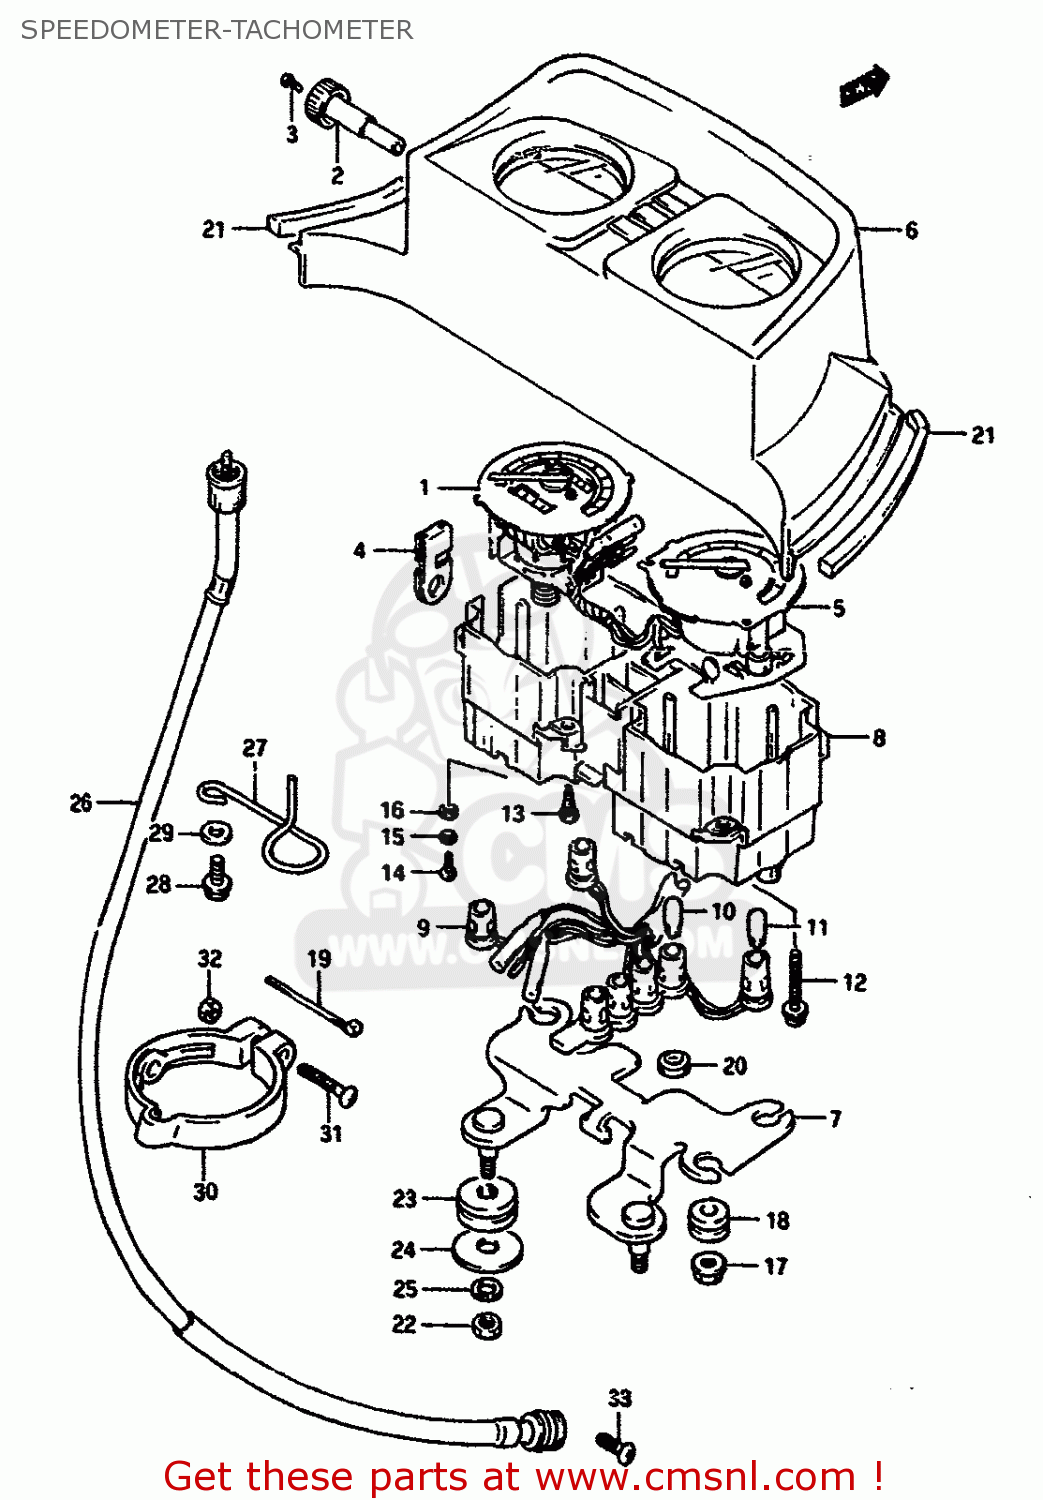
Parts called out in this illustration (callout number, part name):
1	SPEEDOMETER (KILO)
2	KNOB
3	SCREW,TRIP KNOB
4	CUSHION,METER
5	TACHOMETER
6	HOOD,METER
7	BRACKET
8	CASE,METER
9	SOCKET
10	BULB(12V1.7W,WB372,T7)
11	BULB(12V3W,WB371,T7)
12	SCREW
13	SCREW
14	SCREW
15	LOCK WASHER
16	WASHER 3.3X8X0
17	NUT
18	CUSHION,METER
19	CLAMP
20	CAP
21	CUSHION
22	NUT
23	CUSHION
24	WASHER (6.5X24X1.6)
25	WASHER,LOCK
26	CABLE ASSY,SPEEDOMETER
27	GUIDE,CABLE
28	BOLT
29	WASHER
30	CLAMP,SPEEDOMETER CABLE
31	SCREW
32	NUT 5MM
33	SCREW
